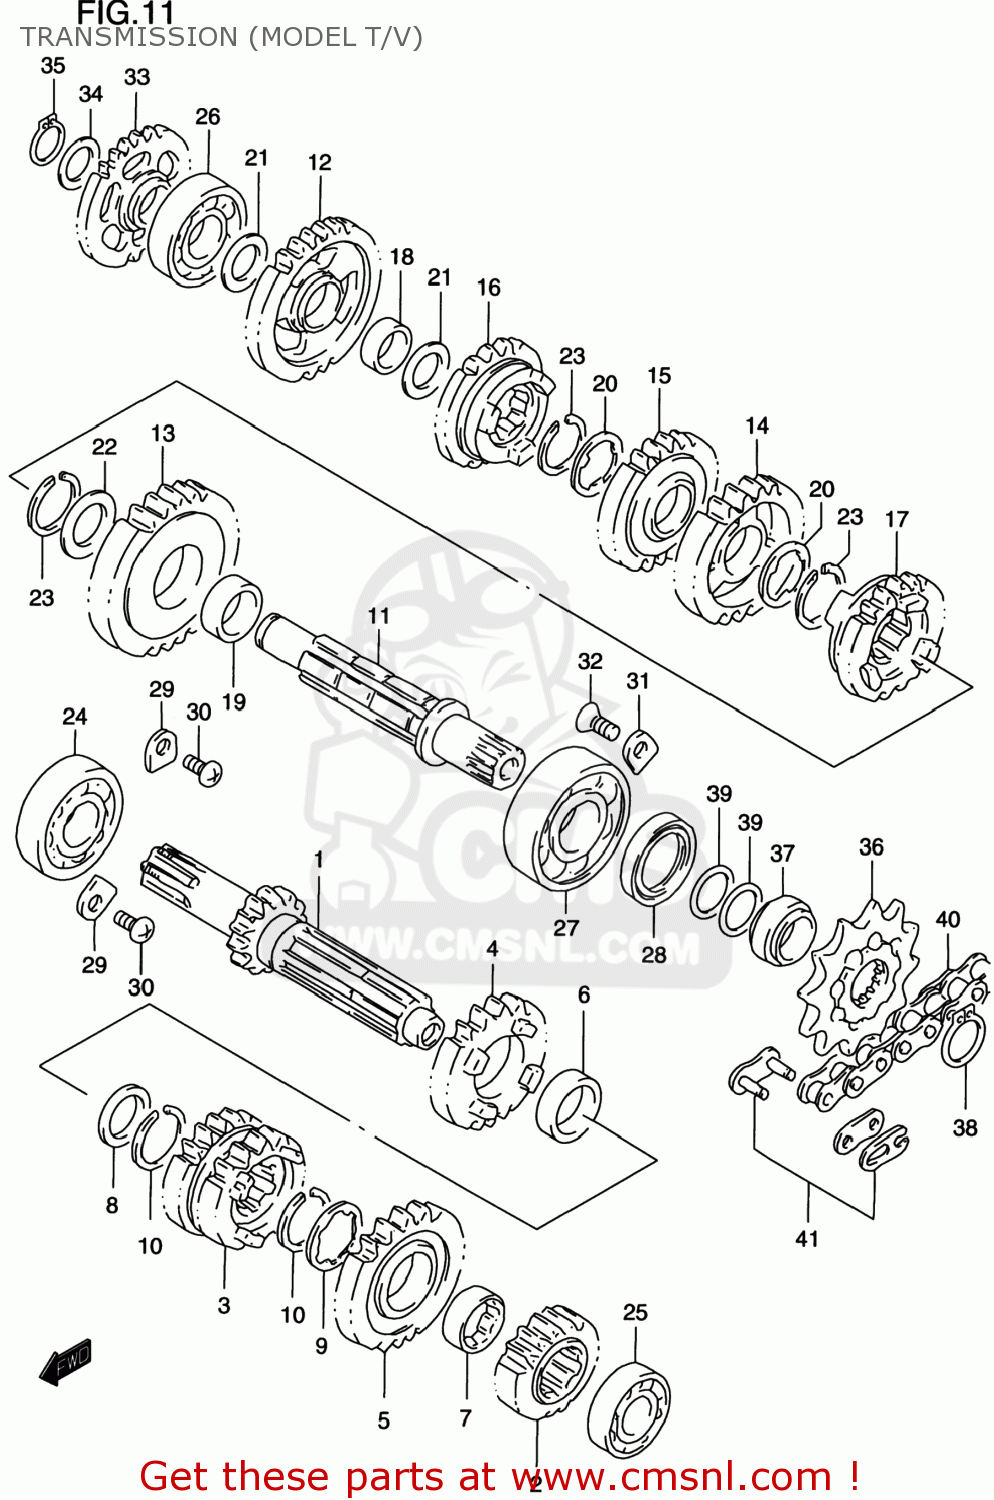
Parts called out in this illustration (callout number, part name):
1	SHAFT,COUNTER(NT:14)
2	GEAR,2ND DRIVE(NT:16)
3	GEAR,THIRD & FOURTH DRIVE
4	GEAR,FIFTH DRIVE (NT:19)
5	GEAR,SIXTH DRIVE (NT:20)
6	BUSH(22X26X9)
7	BUSH,6TH DRIVE GEAR
8	SHIM
9	WASHER,LOCK
10	CIRCLIP
11	SHAFT,DRIVE
12	GEAR,1ST DRIVEN(NT:30)
13	GEAR,2ND DRIVEN(NT:28)
14	GEAR,3RD DRIVEN(NT:26)
15	GEAR,4TH DRIVEN(NT:24)
16	GEAR,5TH DRIVEN(NT:20)
17	GEAR,6TH DRIVEN(NT:19)
18	BUSH(17X20X9)
19	BUSH(22X26X9)
20	WASHER
21	WASHER,THRUST
22	WASHER,THRUST
23	CIRCLIP
24	BEARING(20X47X12)
25	BEARING
26	BEARING(17X40X9.5)
27	BEARING(20X52X12.5)
28	SEAL,OIL(28X38X6)
29	RETAINER
30	SCREW
31	RETAINER,COUNTER BEARING,R
32	SCREW
33	GEAR,KICK STARTER IDLE
34	SHIM
35	CIRCLIP,17MM
36	SPROCKET,ENGINE
37	SPACER,ENGINE SPROCKET
38	CIRCLIP
39	O RING(D:1.9,ID:19.8)
40	CHAIN ASSEMBLY DID520DM.11
41	JOINT SET,CHAIN
